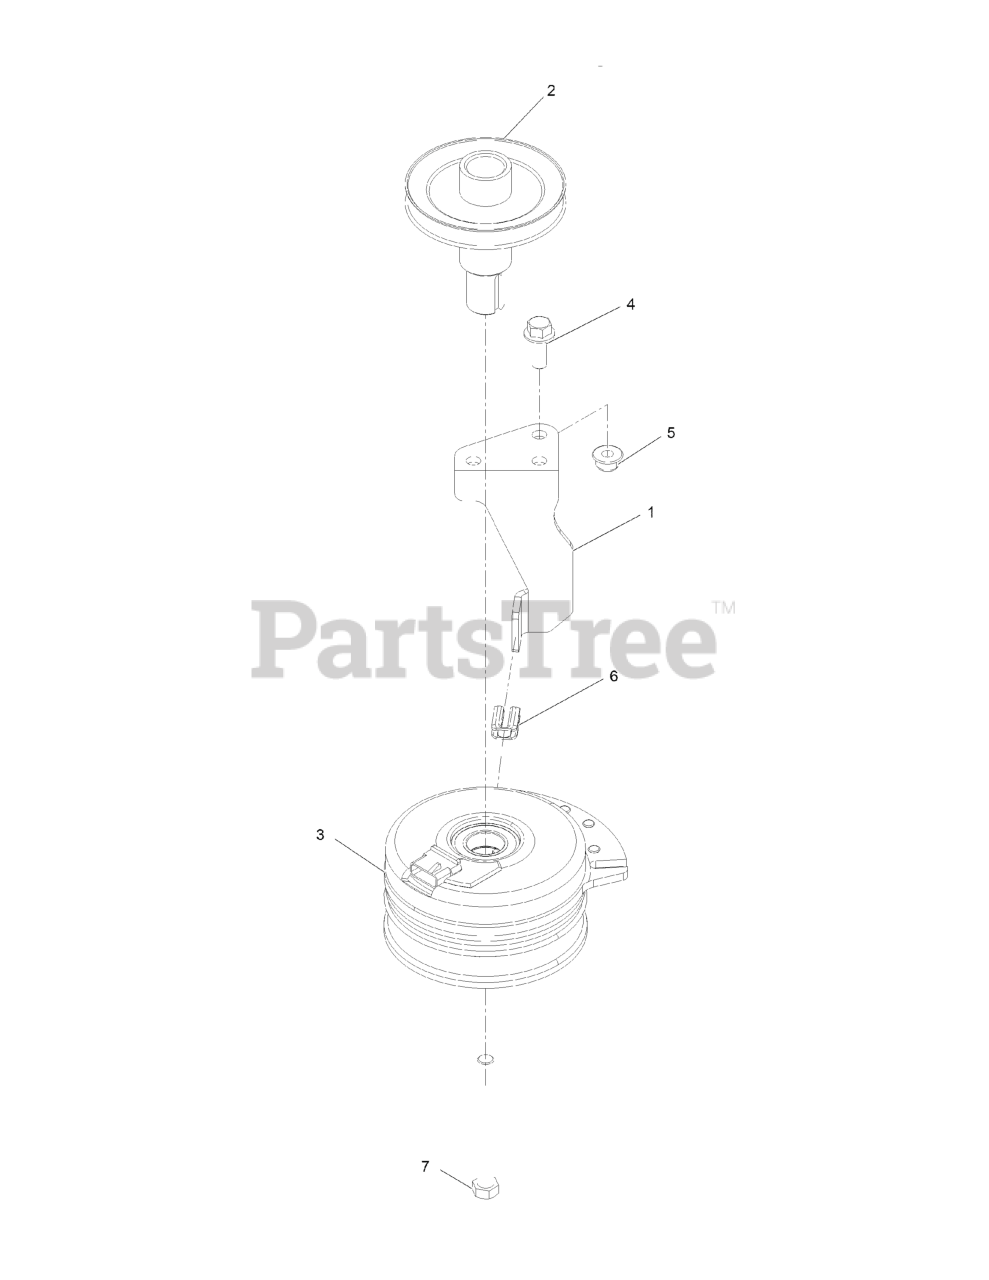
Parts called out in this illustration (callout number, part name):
1	Stop - Clutch (Narrow)
2	Pulley-Engine
3	CLUTCH-ELECTRIC
4	SCREW-HHF 3/8-16 X 1
5	NUT-HF, NI
6	ISOLATOR-CLUTCH
7	SCREW-HH
